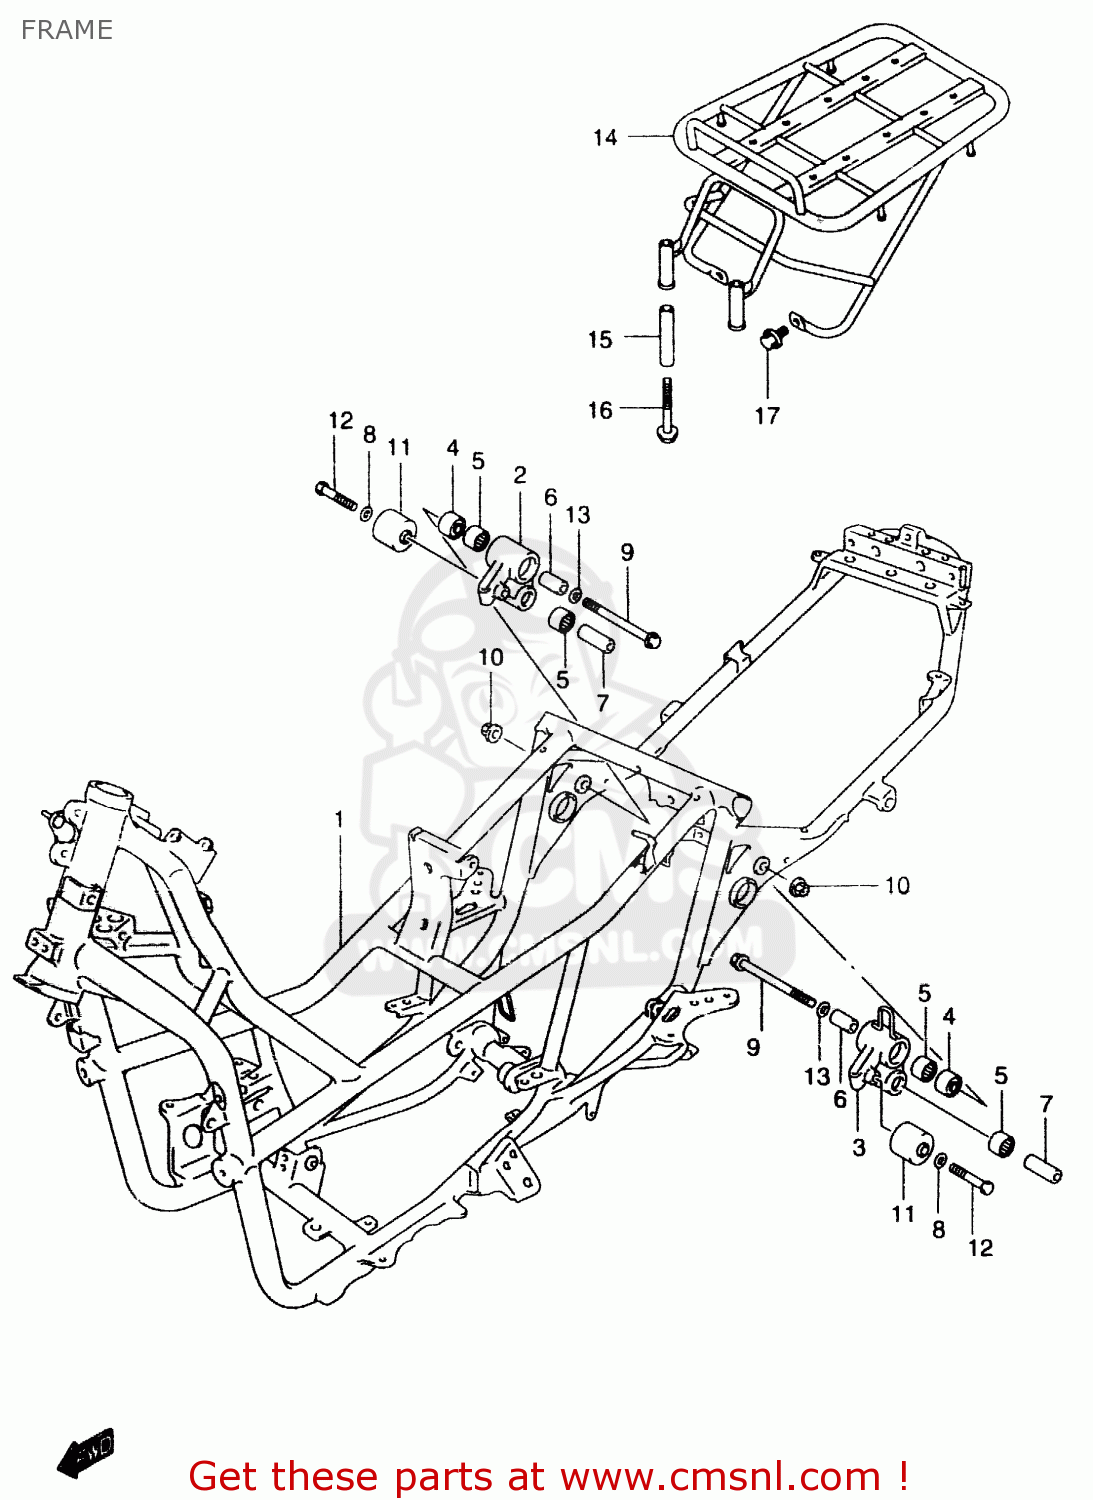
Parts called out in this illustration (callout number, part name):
1	FRAME
2	BRACKET SET, CRANKCASE RH
3	BRACKET SET, CRANKCASE LH
4	BUSH
5	BEARING(20X27X26)
6	SPACER,CRANKCASE BRACKET
7	SPACER,CRANKCA
8	WASHER(12.5X35X3.2)
9	BOLT(12X118)
10	NUT 12MM
11	CUSHION,SWING STOP
12	BOLT(12X58)
13	WASHER
14	CARRIER SET,SP
15	SPACER, LOWER
16	BOLT(8X85)
17	BOLT(8X65)
